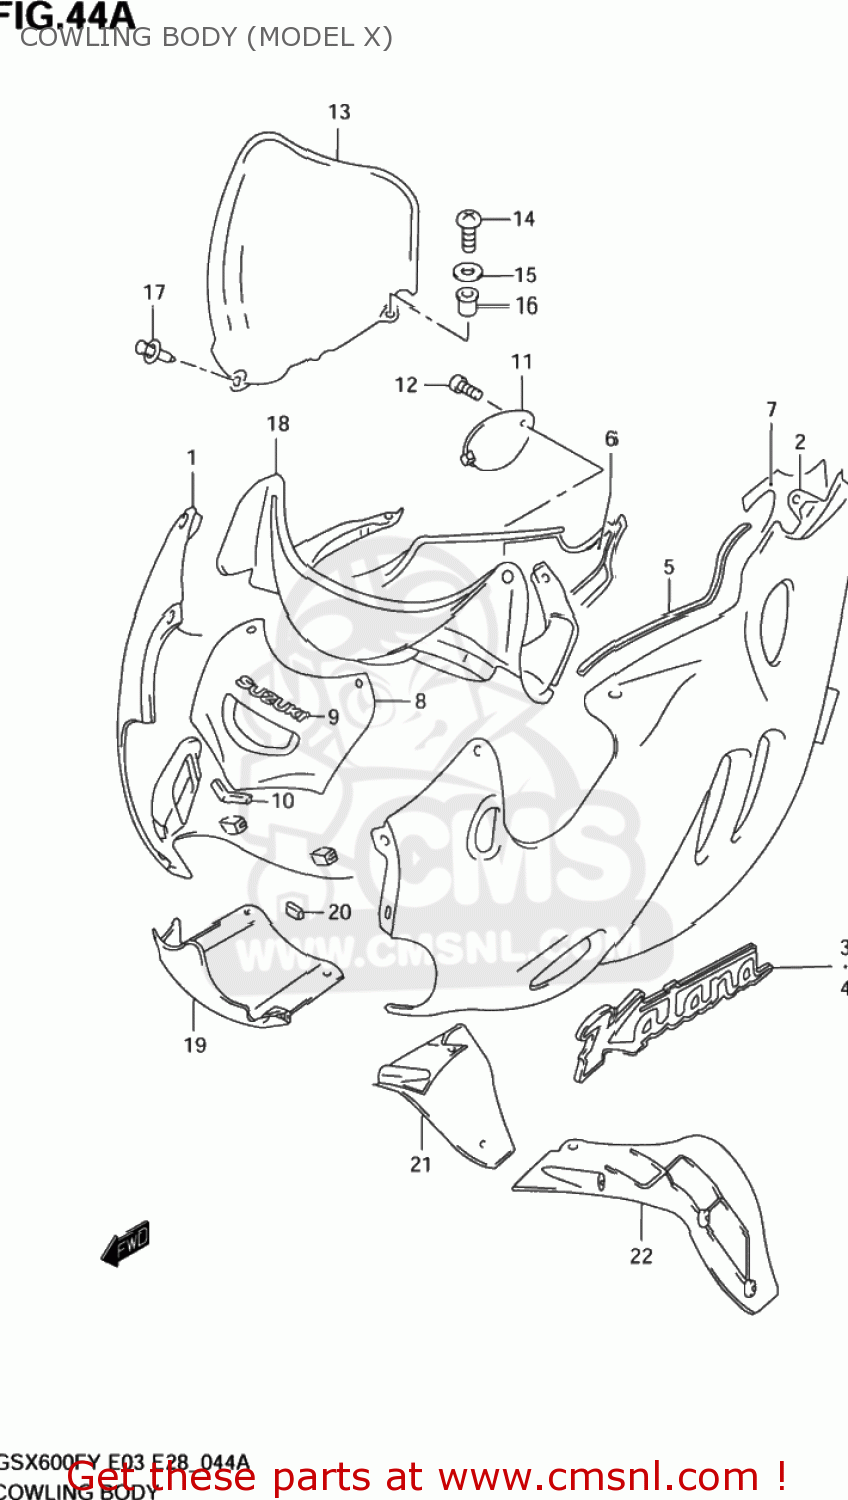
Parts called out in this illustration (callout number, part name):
1	COWLING ASSY,SIDE,R
2	COWLING ASSY,SIDE,L
3	EMBLEM,COWLING SIDE,KATANA,R
4	EMBLEM,COWLING SIDE,KATANA,L
5	MOLD,COWLING
6	SHIELD,COWLING COVER,R
7	SHIELD,COWLING COVER,L
8	PANEL,COWLING CTR UPR
9	EMBLEM,SUZUKI(SILVER)
10	CUSHION,CTR PANEL UPR
11	LID,OIL
12	SCREW(6X16)
13	WINDSCREEN
14	SCREW(5X14)
15	WASHER
16	NUT
17	CLIP(BLACK)
18	PANEL,METER
19	PANEL,COWLING CTR LWR
20	CUSHION,CENTER PANEL,LOWER
21	PANEL,COWLING INNER,R
22	PANEL,COWLING INNER,L
